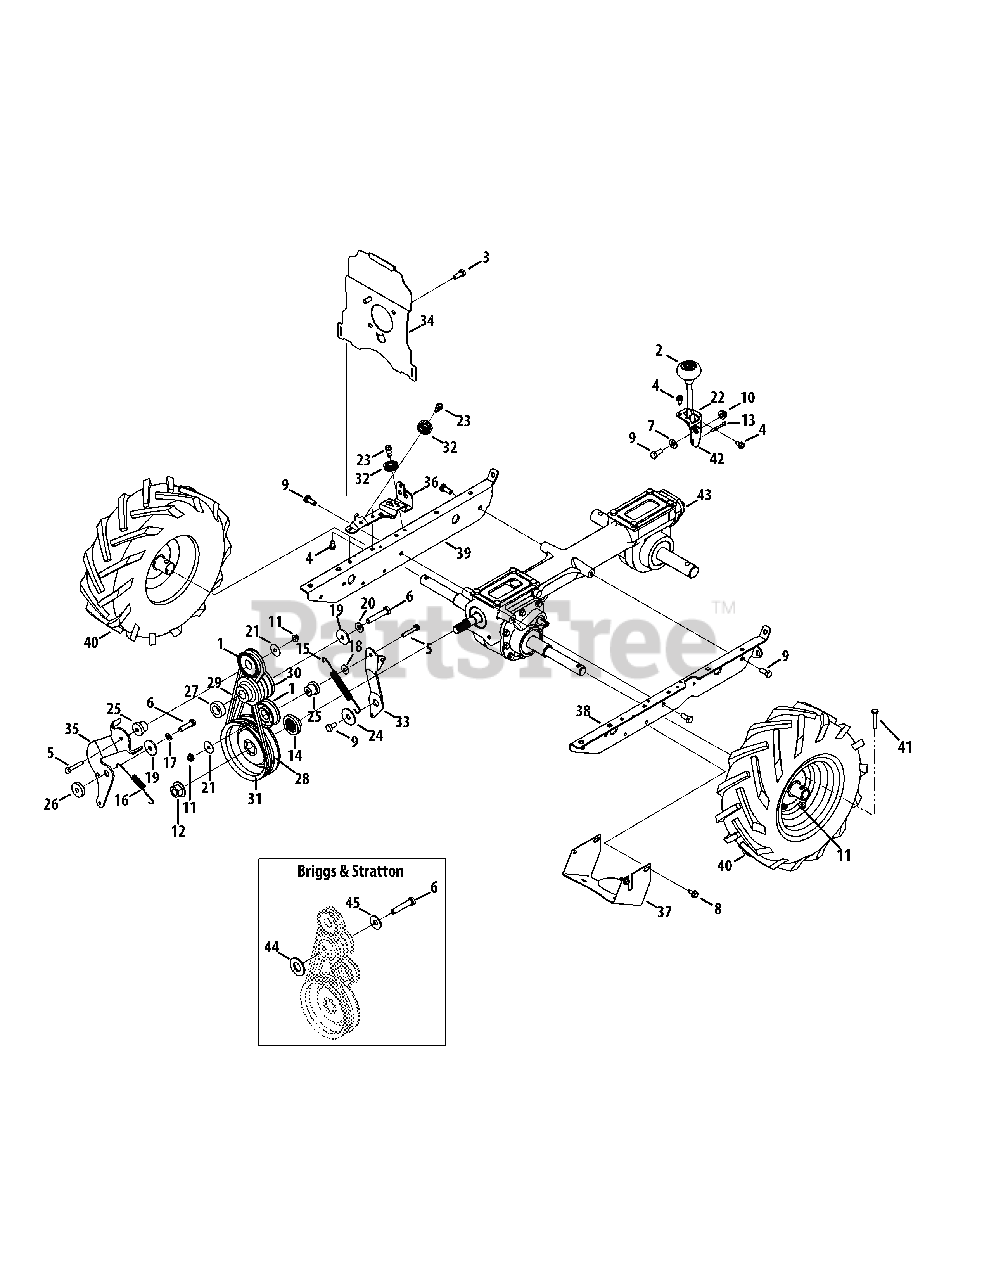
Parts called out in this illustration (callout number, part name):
1	Idler Pulley Assembly, 1.917 OD
2	Knob, Shift
2	Rod, Shift
3	Hex Head Screw, 5/16-24 x .625
4	Screw, 1/4-20 x 0.500
5	Hex Head Screw, 1/4-20 x 1.50
6	Hex Screw, 3/8-24 x 2.25 (B&S)
7	Pivot Spacer
8	Self Tapping Screw, 1/4-14 x .625
9	Hex Head Screw, 5/16-18 x .75, Patch
10	Flangelock Nut, 5/16-18, B&S
11	Flangelock Nut, 1/4-20
12	Flange Nut, 9/16-18
13	Cotter Pin, 5/32 x 1.25
14	Pulley Hub, 5/8 SPLINE
15	Extension Spring, .480 OD x 5.00 LG
16	Extension Spring, LT5 PTO
17	Washer, Lock, 5/16
18	Washer, Flat, .28 x .74 x .063
19	Washer, Flat, .330 x 1.25 x .120
20	Washer, .396 x 1.140 x .095, B&S
21	Washer, Flat, .265 x 1.0 x .030
22	Pivot Mounting Bracket
23	Screw, Shoulder, 1/4-28 x .342 x .335
24	Forward Idler Pivot Spacer
25	Spacer, Shoulder, .260 x .785 x .538
26	Reverse Idler Pivot Spacer
27	Spacer, .766 ID x 1.25 OD x .415
28	V Belt, 4L x 25.375 LG
29	V Belt, 3L x 29.125 LG
30	Engine Pulley, 3L & 4L
31	Transmission Pulley
32	Cable Roller
33	Forward Idler Bracket
34	Cover Mounting Plate
35	Reverse Idler Bracket
36	Pulley Mounting Bracket
37	Pulley Shield
38	LH Mount Frame
39	RH Mount Frame
40	Wheel, 13 x 5 x 6
41	Hex Head Screw, 1/4-20 x 1.5
42	Pivot Bracket
43	Transmission Assembly
44	Washer, Flat, .760 x 1.50 x .120 (B&S)
45	Washer, Bell, .396 x 1.140 x .095 (B&S)
